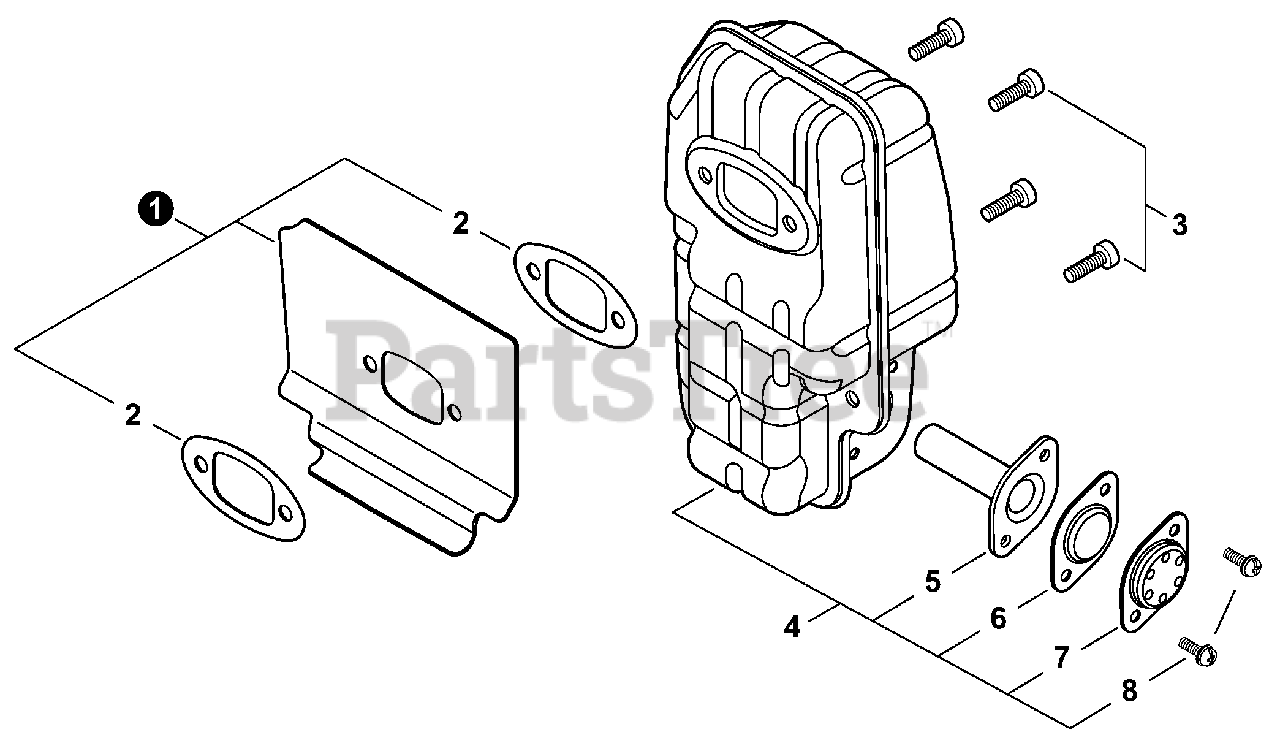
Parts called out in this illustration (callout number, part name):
1	SHIELD ASSY, EXHAUST HEAT
2	GASKET, EXHAUST
3	BOLT 6×20
4	MUFFLER ASSY
5	PIPE, EXHAUST
6	SCREEN, SPARK ARRESTER
7	GUIDE, EXHAUST
8	SCREW M4×12
